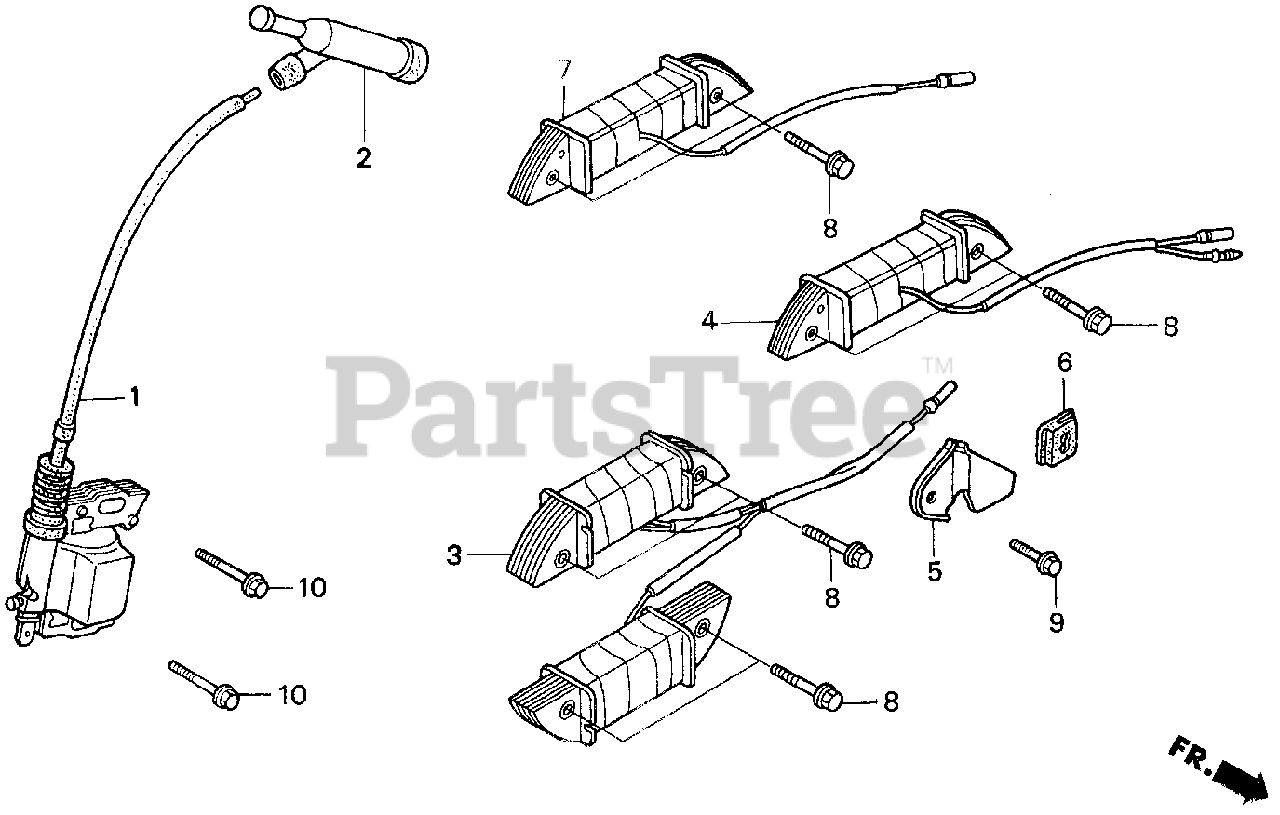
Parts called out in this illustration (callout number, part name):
1	COIL ASSY., IGNITION
2	CAP ASSY., NOISE SUPPRESSOR
3	COIL ASSY., LAMP (12V/50W)
5	CLAMP, WIRE
6	GROMMET, WIRE
8	BOLT, FLANGE (6X28)
9	BOLT, FLANGE (5X10)
10	BOLT, FLANGE (6X25)
